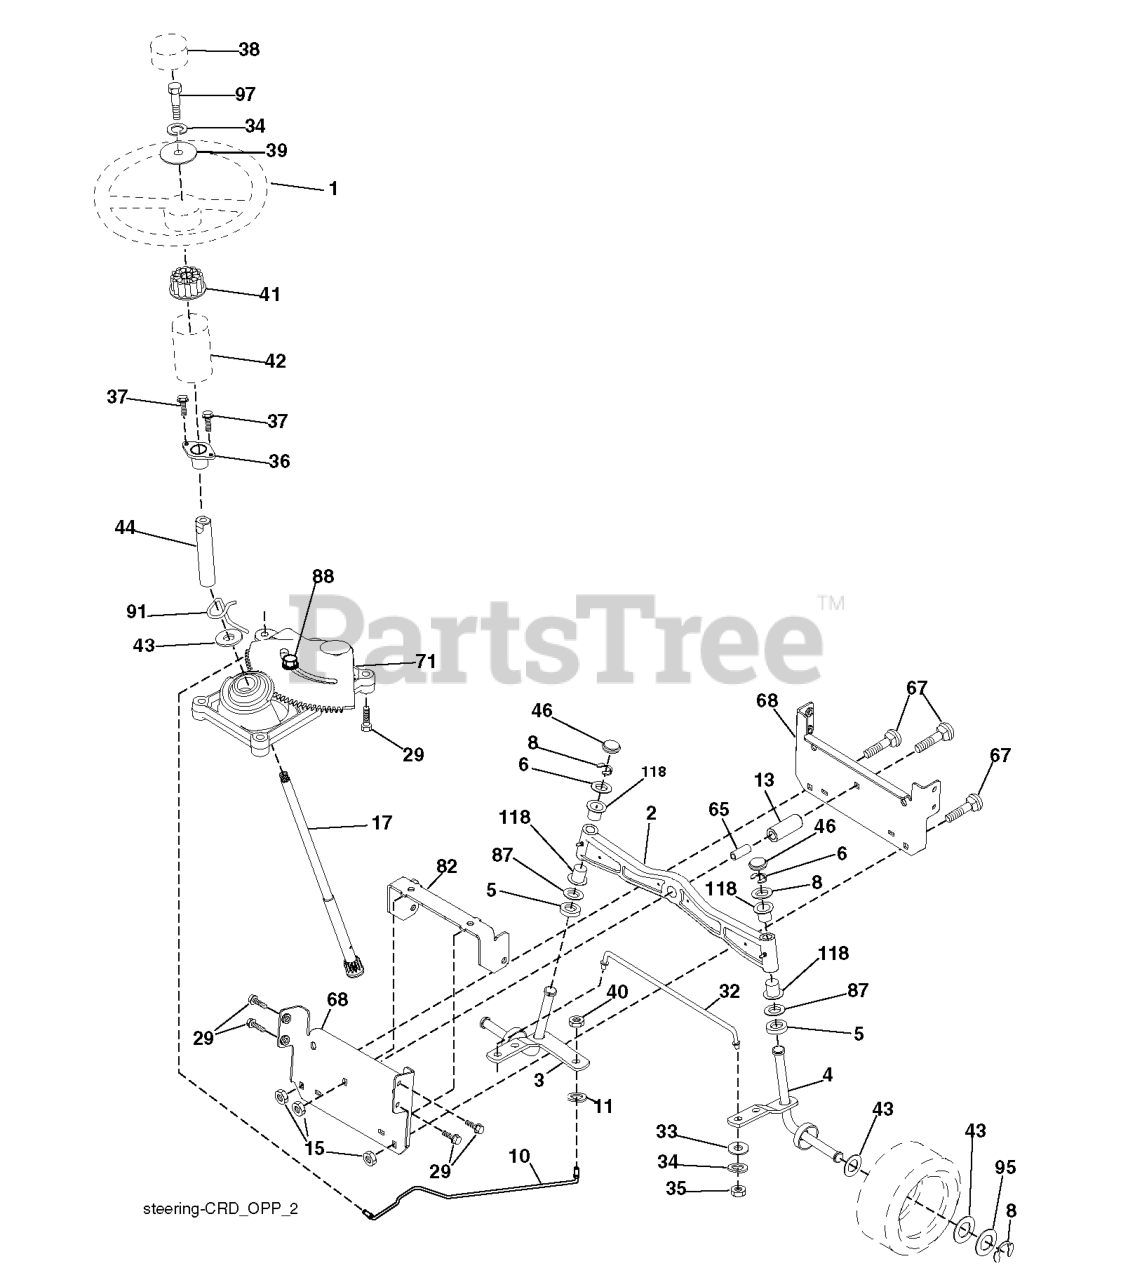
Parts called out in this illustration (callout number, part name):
1	WHEEL.STEERING.OPP.BLACK
2	AXLE.ASM.LT.CAST.LGHTWGHT
3	SPINDLE.ASM.LH.15"TIRES
4	SPINDLE.ASM.RH.15"TIRES
5	THRUST WASHER
10	DRAGLINK.15".TIRES.2001
11	WASHER, LOCK 3/8
13	TUBE, PIVOT AXLE
15	NUT LOCK FLG 3/8-16 UNC
17	SHAFT STEERING SPLINE
29	SCREW, 3/8-16X3/4
32	ROD.ASM.TIE.BALL.JOINT.NOVAN
33	WASHER M
34	WASHER.LOCK.HVY.HLCL.SPR.5/16
35	NUT, CROWNLOCK
36	BUSHING, STEERING
37	SCREW.TT.#10-32X.5.3/8.FLANGE
38	CAP.WHEEL.STEER.OPP.BLK
39	WASHER.11/32
40	NUT CROWNLOCK 3/8-24
41	ADAPTER, WHEEL STNG..
42	BOOT.STEERING.SHAFT.BLACK
44	SHAFT.EXTEN.STRG.SPLINE
46	CAP.SPINDLE.BLACK
65	SPACER.BRACE.AXLE
67	BOLT CARRIAGE
68	BRACE.AXLE.15"TIRES
71	STEERING ASM
82	BRACKET.SUSP.CHASSIS.FRONT.15
87	WASHER, FLAT .781 X 1 1/2"
88	BOLT, SHOULDER 7/16-20
91	CLIP.STEERING
95	WASHER.HARDENED
97	BOLT 5/16-18 X 4 W/PATCH
118	BUSHING, AXLE CAST
